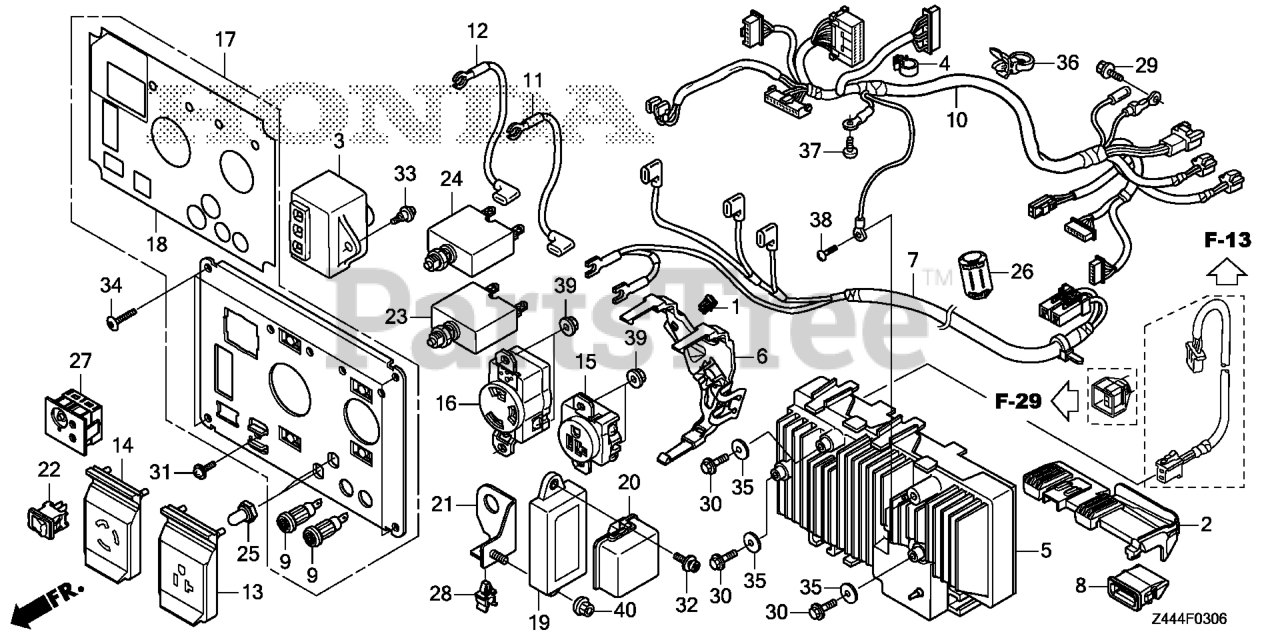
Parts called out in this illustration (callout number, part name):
1	CLIP, TUBE
2	RUBBER B, TANK MOUNTING
3	SPARK UNIT
4	CLIP, HARNESS
5	INVERTER UNIT
6	BRACKET, INVERTER HARNESS
7	SUB-WIRE HARNESS ASSY.
8	COVER, CONNECTOR
9	SOCKET, COMPOSITE
10	WIRE HARNESS ASSY., CONTROL
11	WIRE, TERMINAL
12	WIRE, TERMINAL
13	COVER, RECEPTACLE (20A-125V)
14	COVER, RECEPTACLE (30A-125V)
15	RECEPTACLE (20A/125V)
16	RECEPTACLE (30A/125V)
17	PANEL, CONTROL
18	MARK, CONTROL PANEL
19	SENSING UNIT (CO)
20	COVER, SENSING UNIT PROOF (CO)
21	BRACKET, SENSOR UNIT (CO)
22	SWITCH, AUTO-THROTTLE (OTAX)
23	PROTECTOR, CIRCUIT (20A) (WHITE)(TYCO)
23	PROTECTOR, CIRCUIT (20A) (BLACK)(JOEMEX)
24	PROTECTOR, CIRCUIT (30A) (BLACK)
24	PROTECTOR, CIRCUIT (30A) (WHITE)
25	COVER, CIRCUIT PROTECTOR
26	FILTER, SUB NOISE (AC)
27	LED ASSY., INDICATER
28	CLIP, TUBE
29	BOLT, FLANGE (5X10)
30	BOLT, FLANGE (5X12)
31	SCREW, PAN (5X12) (GROUND CABLE)
32	BOLT-WASHER (5X15) (TORX)
33	SCREW, PAN (5X13)
34	SCREW, TAPPING (5X16) (TORX)
35	WASHER, PLAIN (20MM)
36	BAND (100MM) (BLACK)
37	SCREW, PAN (5X8)
38	SCREW, PAN (5X10)
39	NUT, FLANGE (4MM)
40	NUT, FLANGE (5MM)
